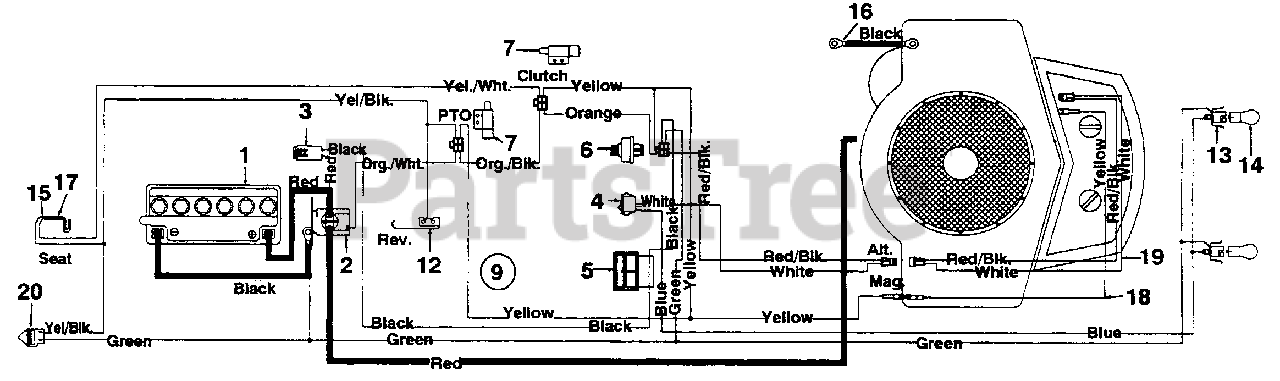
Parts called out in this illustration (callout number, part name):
1	Battery
2	Solenoid
3	Fuse 7.5 Amps
4	Light Switch
5	Ammeter
6	Ignition Switch
7	Safety Switch
9	Wire Harness
12	Safety Switch (Reverse)
13	Socket
14	Bulb (Headlight)
15	Safety Switch (Seat)
16	Ground Wire 7.5" Lg.
17	Safety Switch (Seat)
18	Harness Adapter
19	Harness Adapter
20	Safety Switch (Bag)
